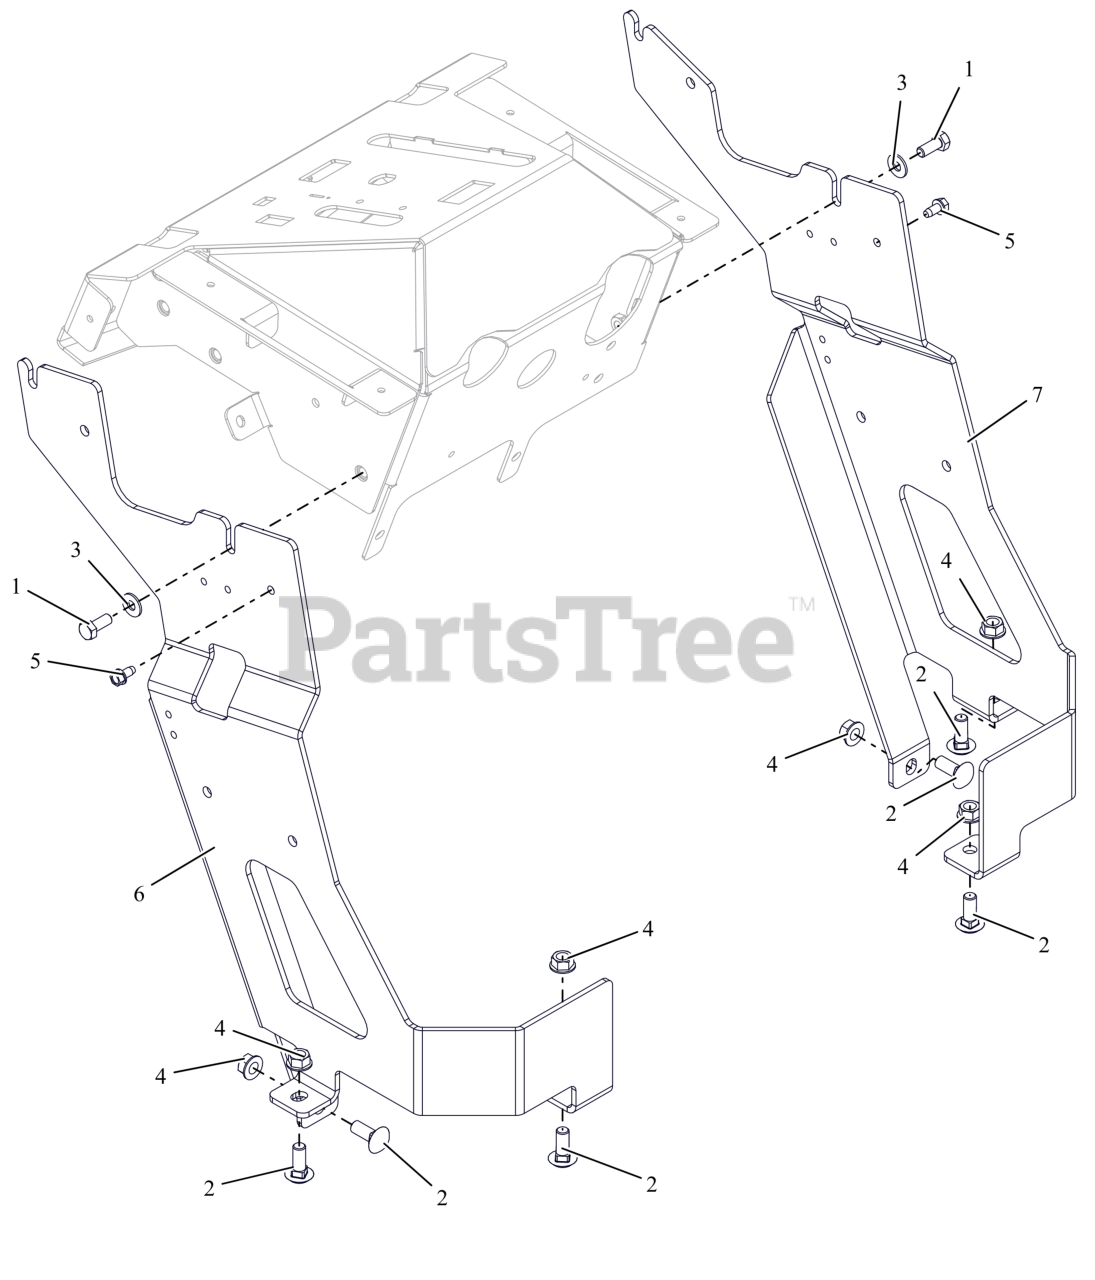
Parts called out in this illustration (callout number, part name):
1	BLT,HEX .31-18X.75 G5 ZCC
2	BLT, RHSN .38-16X1.00 G5 ZCC
3	WSHR, FLT .312X.734X.065 ZCC
4	NUT-LK-CTR-FLG .375-16 GF ZCC
5	SCR-TAP .25-20X.50 HWH ZCC
6	SIDE, RH TOWER (BLACK)
7	SIDE, LH TOWER (BLACK)
